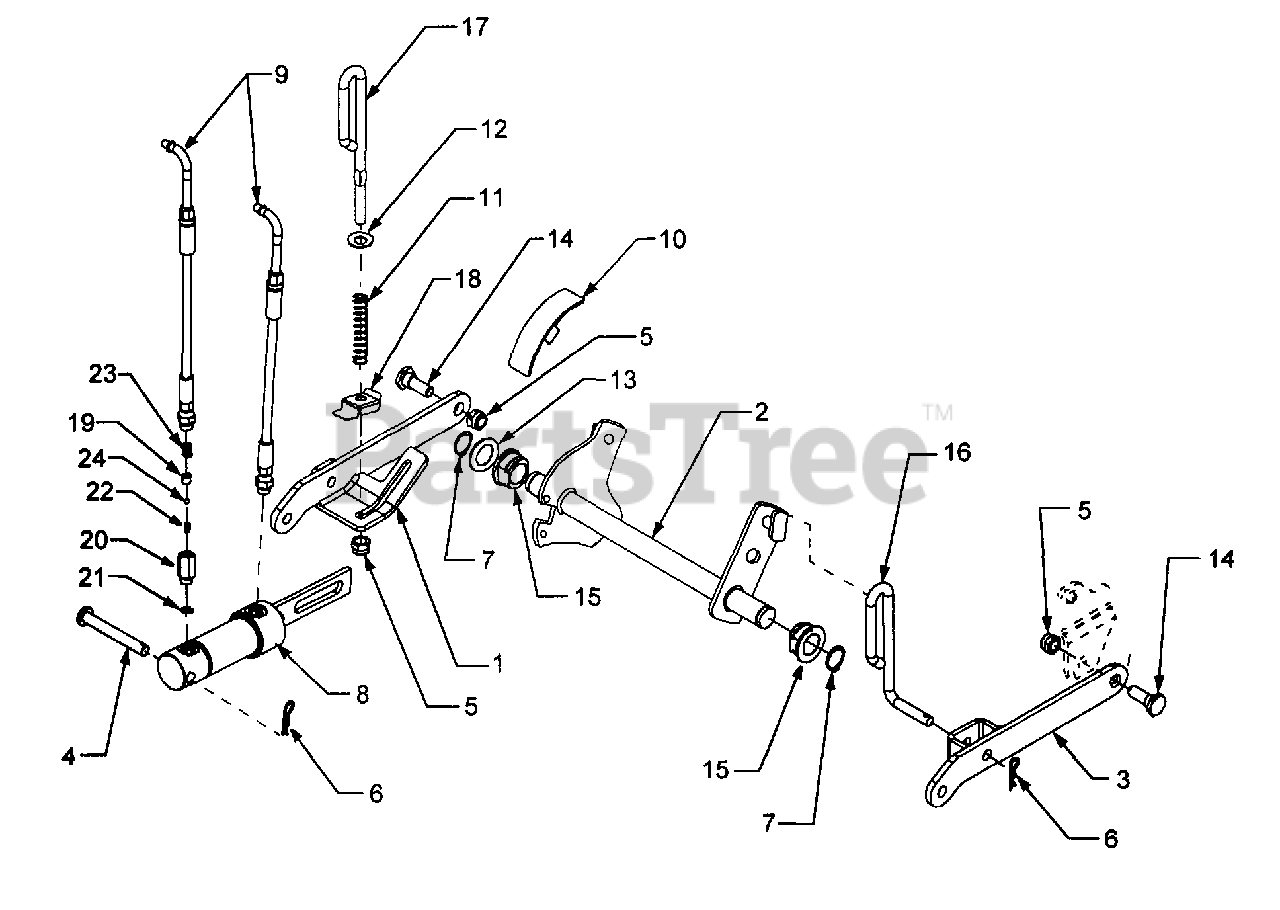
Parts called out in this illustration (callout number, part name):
1	Link, LH Lift
2	Shaft Assembly, Lift
3	Link, RH Lift
4	Pin, Clevis, .5 x 3.75
5	Nut, Hex Lock, 1/2-13
6	Pin, Internal Cotter
7	Snap Ring, 1.0 Dia. Shaft
8	Cylinder, Center Lift
9	Hose, Lift
10	Indicator, Lift Position
11	Spring, Compression
12	Washer, Flat, .536 x .93 x .050
13	Washer. Flat, 1.0 x 1.7 x .10
14	Shoulder Screw
15	Bearing, Flange w/Flats
16	Rod, RH Lift
17	Rod, LH Lift
18	Stop Bracket, Lift Rod
19	Body, Center Check Valve
20	Housing, Check Valve
21	O-Ring
22	Spring, Compression
23	Spring, Compression
24	Ball, Detent
